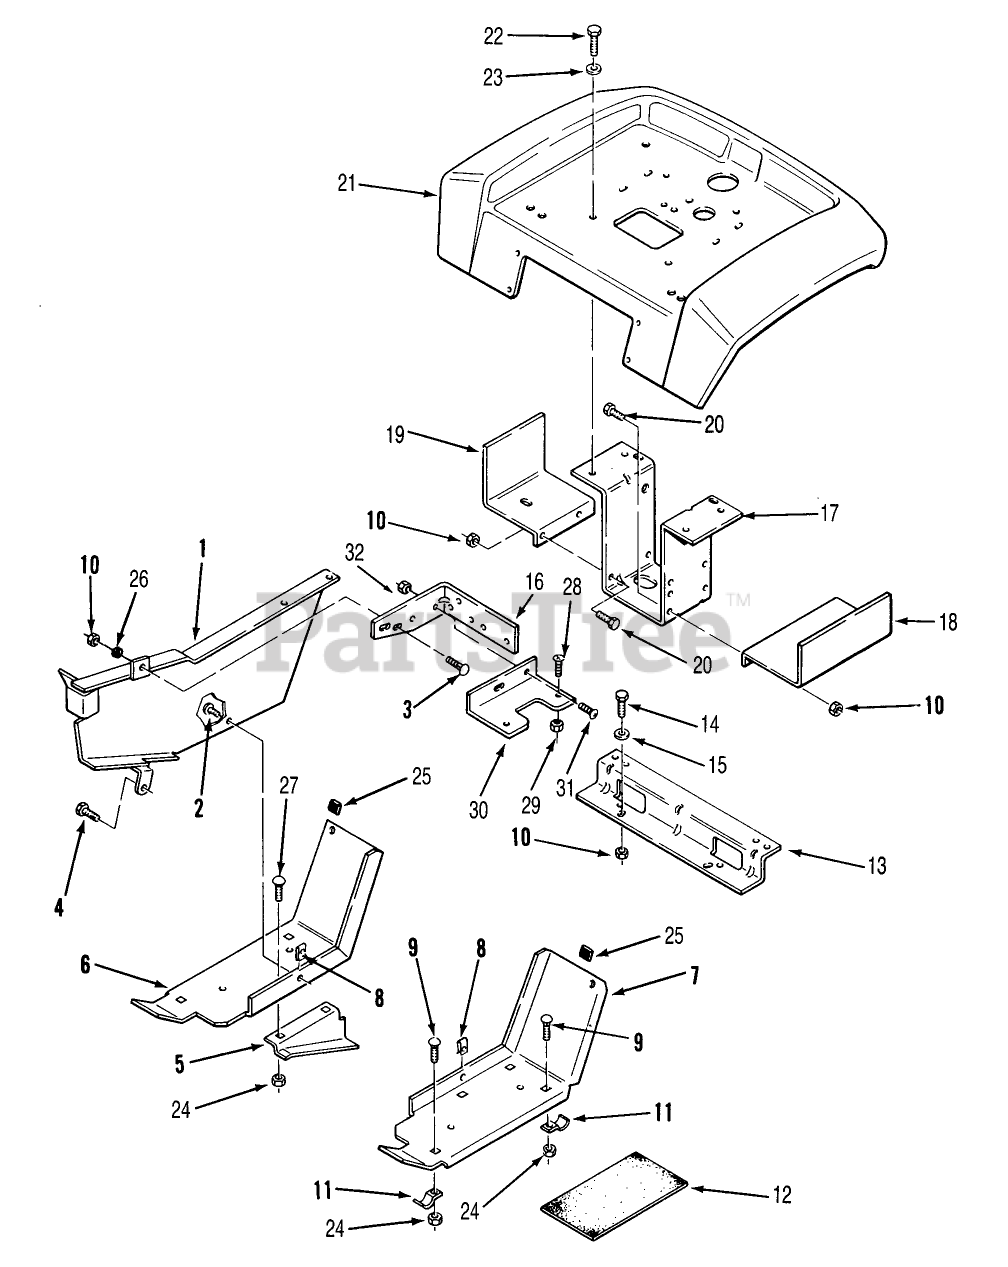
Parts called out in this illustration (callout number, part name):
4	SCREW
7	FOOTREST LH *R
9	BOLT-CARR
11	BRACKET
12	PAD FOOTREST
15	WASHER 5/16 SAE
16	BRACKET-BELT*B
22	SCREW
23	WASHER 5/16 SAE
25	BUMPER
30	BRKT-FUS HLDER*B
